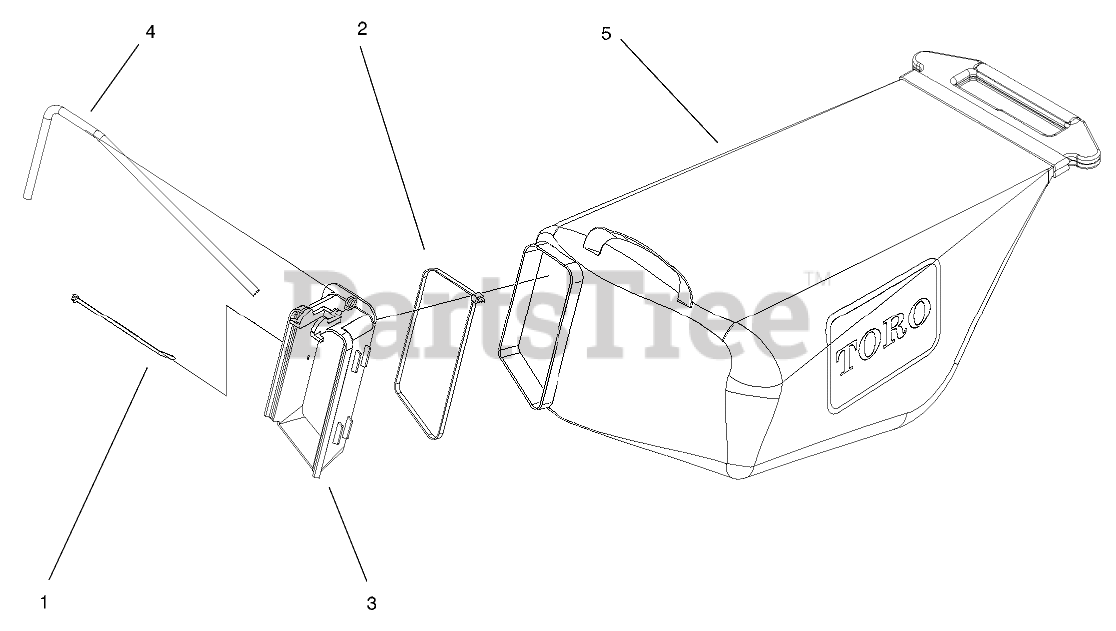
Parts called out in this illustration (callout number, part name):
1	Tie-Strap (only on: 20023, 20023c)
2	Tie Strap (only on: 20023, 20023c)
4	Wire-Support, Bag (only on: 20023, 20023c)
